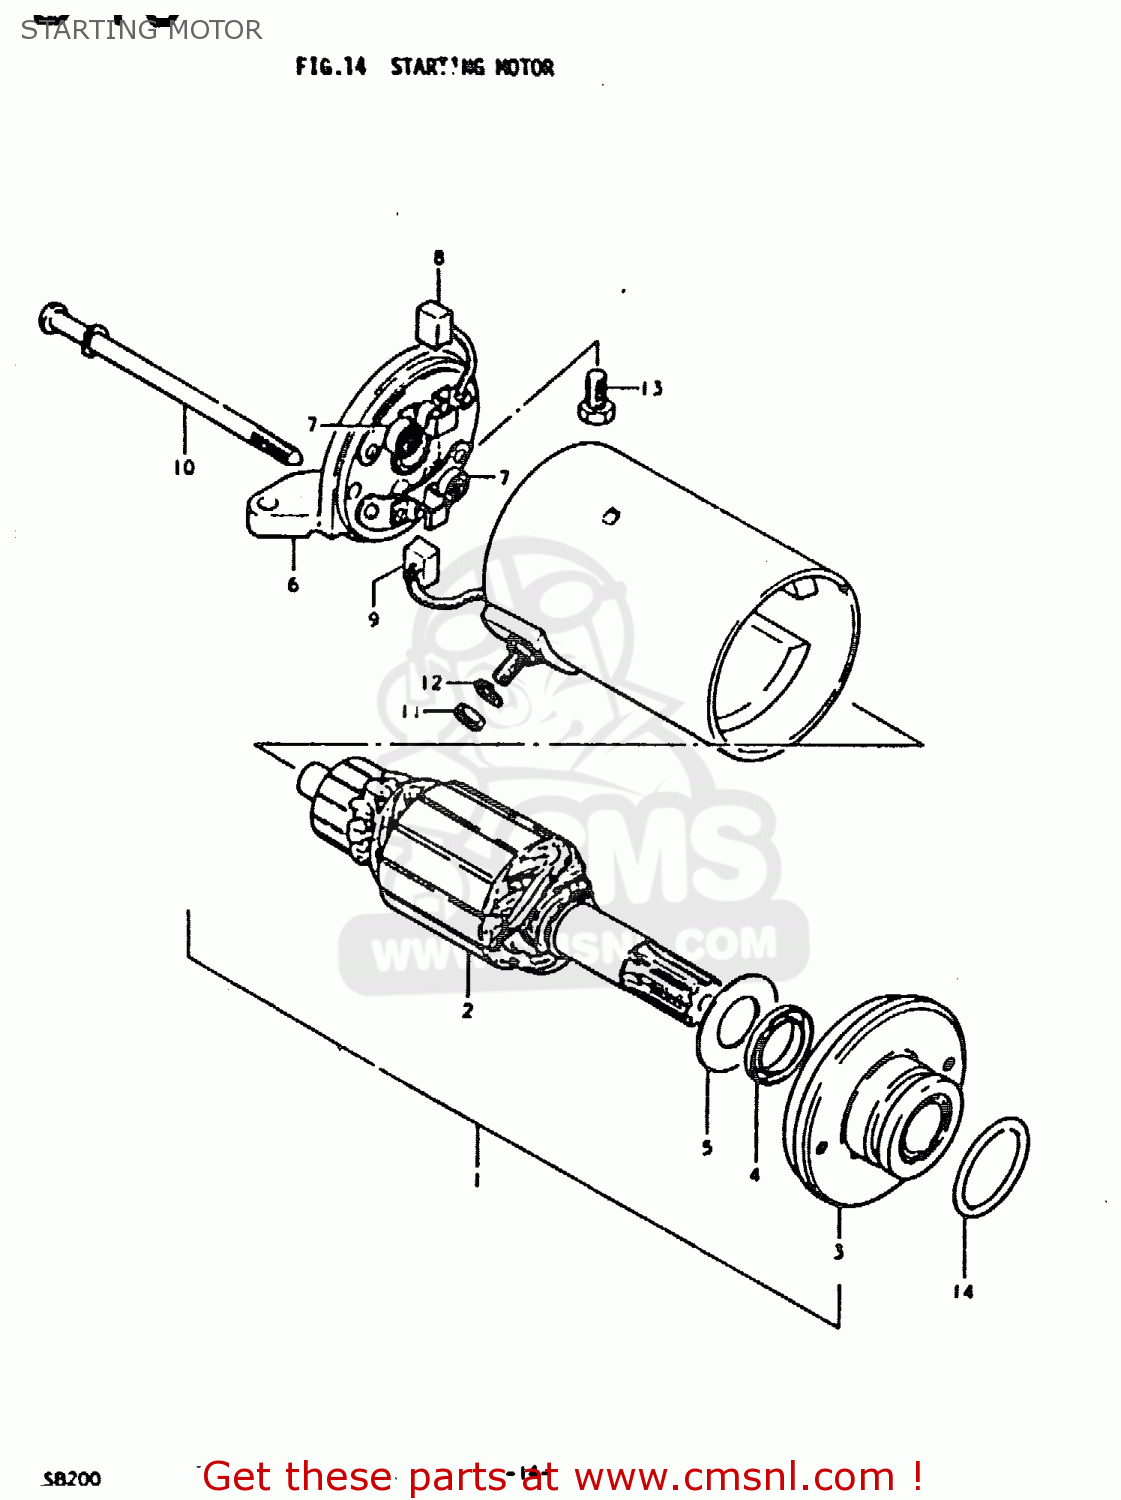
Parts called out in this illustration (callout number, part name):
1	MOTOR ASSY, STARTING
2	ARMATURE
3	HOUSING, DRIVE
4	SEAL,OIL
5	RING,SNAP
6	HOUSING, COMMUTATOR END
7	SPRING
8	BRUSH(-)
9	BRUSH TERMINAL SET
10	BOLT,STARTING MOTOR HOUSING
11	NUT
12	LOCK WASHER
13	SCREW(6X12)
14	O RING(D:2,ID:24.5)
